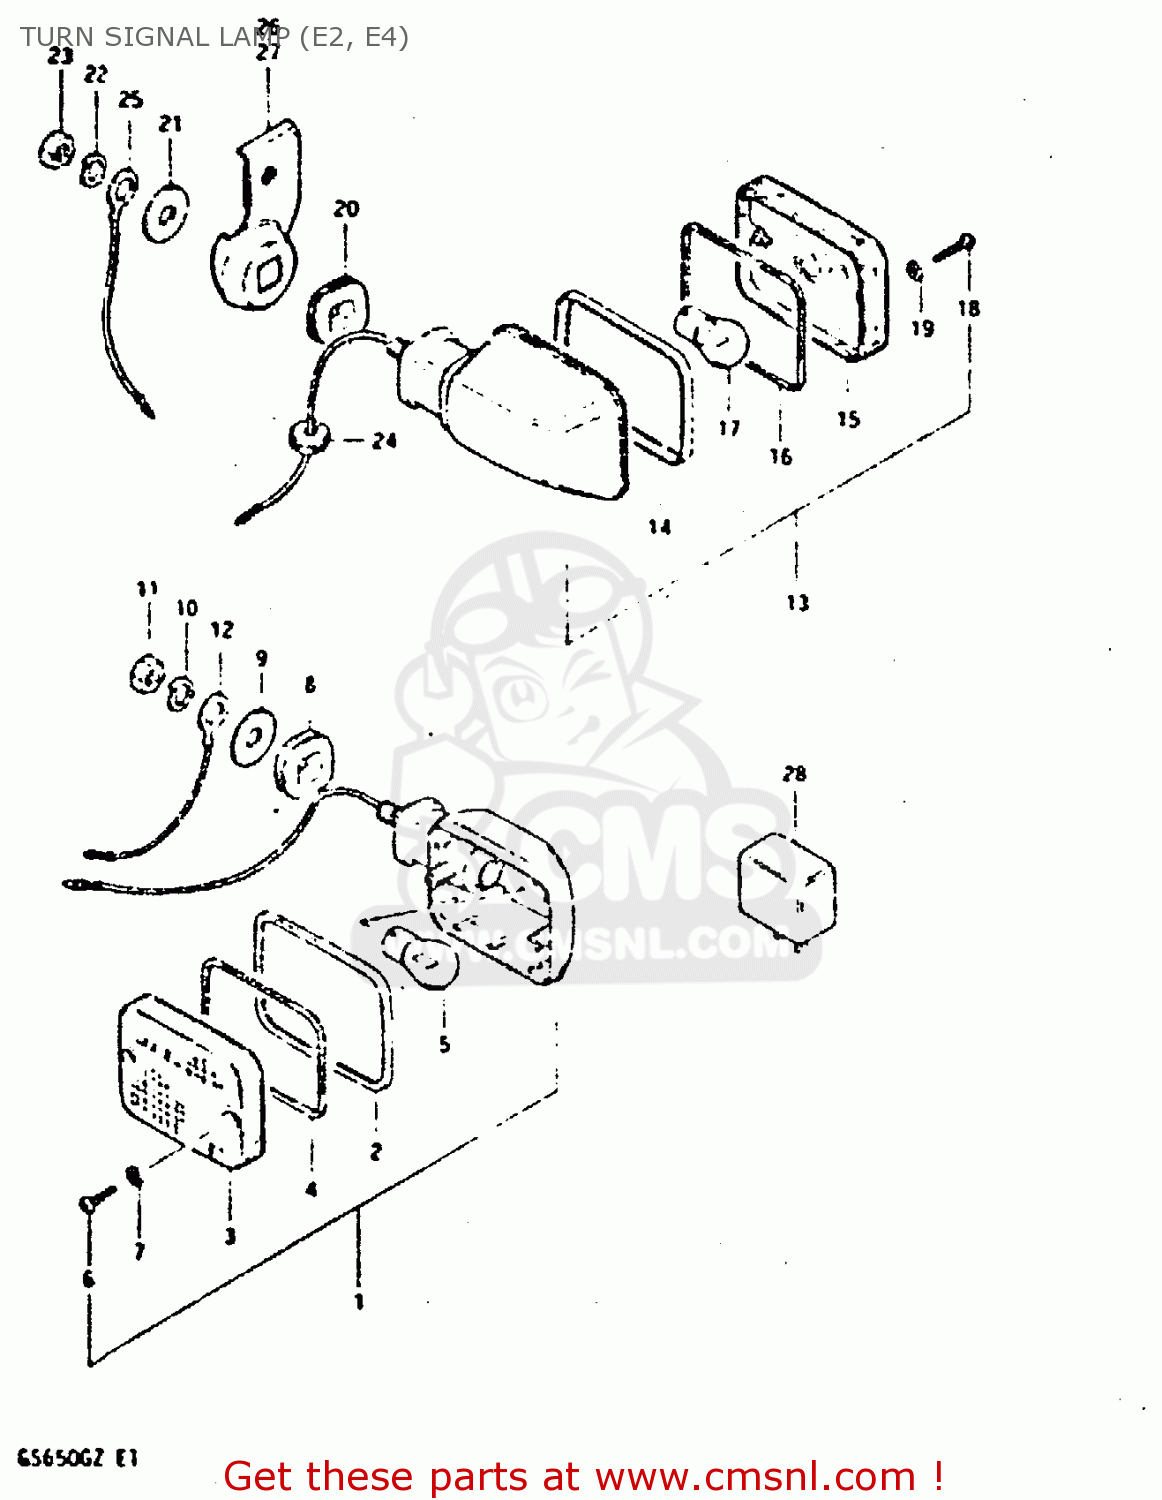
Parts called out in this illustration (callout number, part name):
1	LAMP ASSY,FR T
2	RIM
3	LENS
4	GASKET (NAS)
5	BULB 12V 21W
6	SCREW
7	GASKET (NAS)
8	CUSHION
9	WASHER (10.5X30X2.3)
10	LOCK WASHER
11	NUT
12	WIRE
13	LAMP, REAR TURN SIGNAL
14	RIM
15	LENS
16	GASKET (NAS)
17	BULB 12V 21W
18	SCREW
19	GASKET (NAS)
20	CUSHION
21	WASHER (10.5X30X2.3)
22	LOCK WASHER
23	NUT
24	GROMMET
25	LEAD WIRE,EARTH
26	BRACKET, REAR RH
27	BRACKET, REAR LH
28	RELAY,TURN SIGNAL
